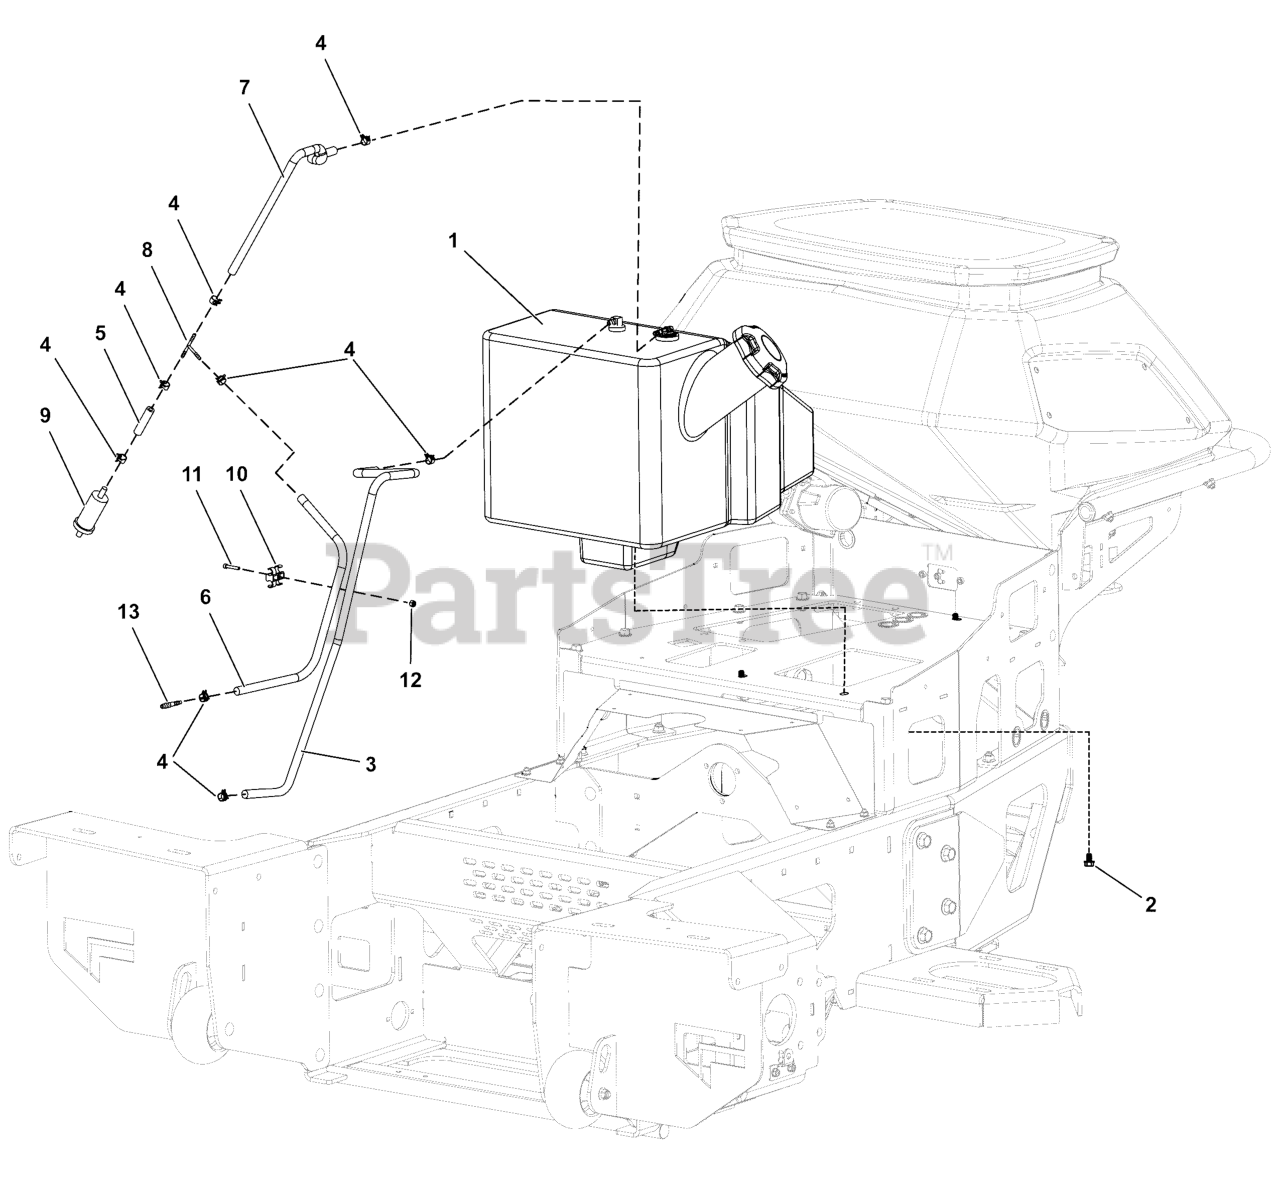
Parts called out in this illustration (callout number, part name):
1	ASM, FUEL TANK, 9 GAL, SPREADER SPRAYER
2	SCR-CAP, HSWH .3125"-18 X .500" SS188
3	HOSE, FUEL, 1/4" ID X 1/2" OD, 32" LG
4	CLAMP, FUEL LINE 0.50"
5	HOSE, FUEL, 1/4" ID X 1/2" OD, 2" LG
6	HOSE, FUEL, 1/4" ID X 1/2" OD, 22" LG
7	HOSE, FUEL, 1/4" ID X 1/2" OD, 14" LG
8	FITTING, 3/16" TEE, BARB TYPE, HDPE
9	FILTER, Fuel
10	CLIP-T, .375"-.500" BLACK
11	SCR-CAP, SH #8-32 X 1.000" SS188
12	NUT-HEX-NYLK, #8-32 SS188
13	REDUCER, 1/4" TO 3/16" HOSE BARB
